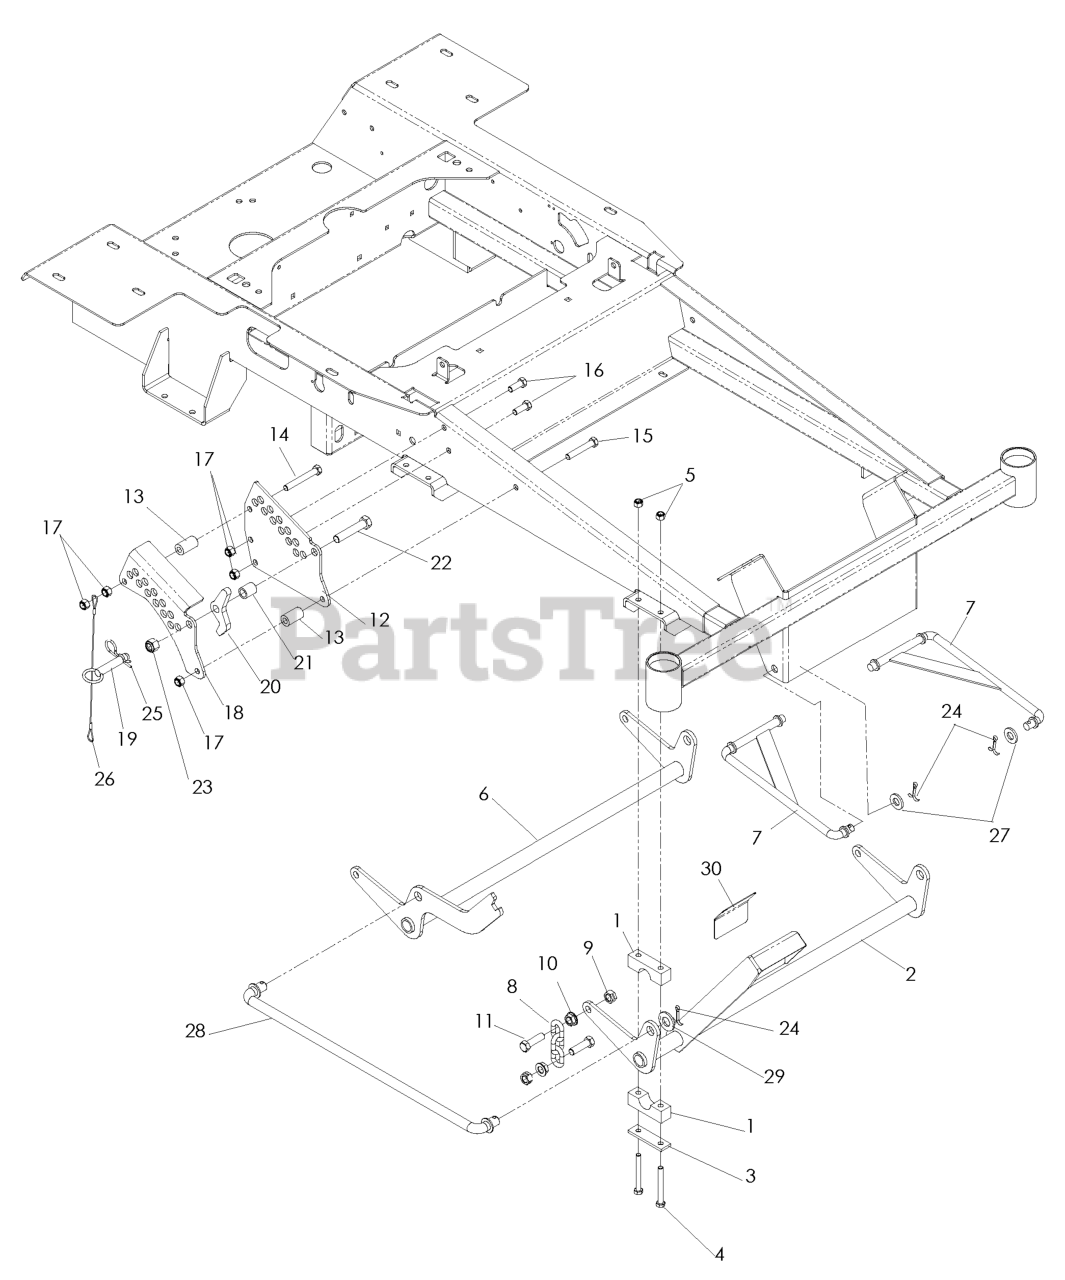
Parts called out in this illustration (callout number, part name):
1	PILLOW BLOCK
2	FRONT LIFT SHAFT
3	REINFORCEMENT BAR
4	HCS 5/16C X 2-3/4
5	NUT 5/16 NYLOC
6	LIFT SHAFT, REAR
7	STRUT LINKAGE
8	LIFT CHAIN - 3 LINK
9	NUT 7/16C CENTERLOCK
10	NUT 7/16C WHIZ
11	HCS 7/16C X 1 1/2
12	HEIGHT ADUST PLATE
13	DECK LIFT SPACER
14	SCREW 3/8C X 2 3/4 HEX CAP
15	HCS 3/8C X 2 1/4
16	HCS 3/8-16X1.GRD.5.ZD
17	NUT 3/8-16 NYLOC
18	HEIGHT ADJUST PLATE, OUTER
19	HITCH PIN
20	PAWL, STOP
22	HEX SCREW 1/2-13 X 2.5" GR 5
23	NUT 1/2-13 HEX NYLOC ZD
24	COTTER PIN
25	HAIRPIN #4
27	WASHER 1/2" FLAT
28	CROSS LINK
29	WASHER 5/8 FLAT
30	ANTI-SKID PAD
